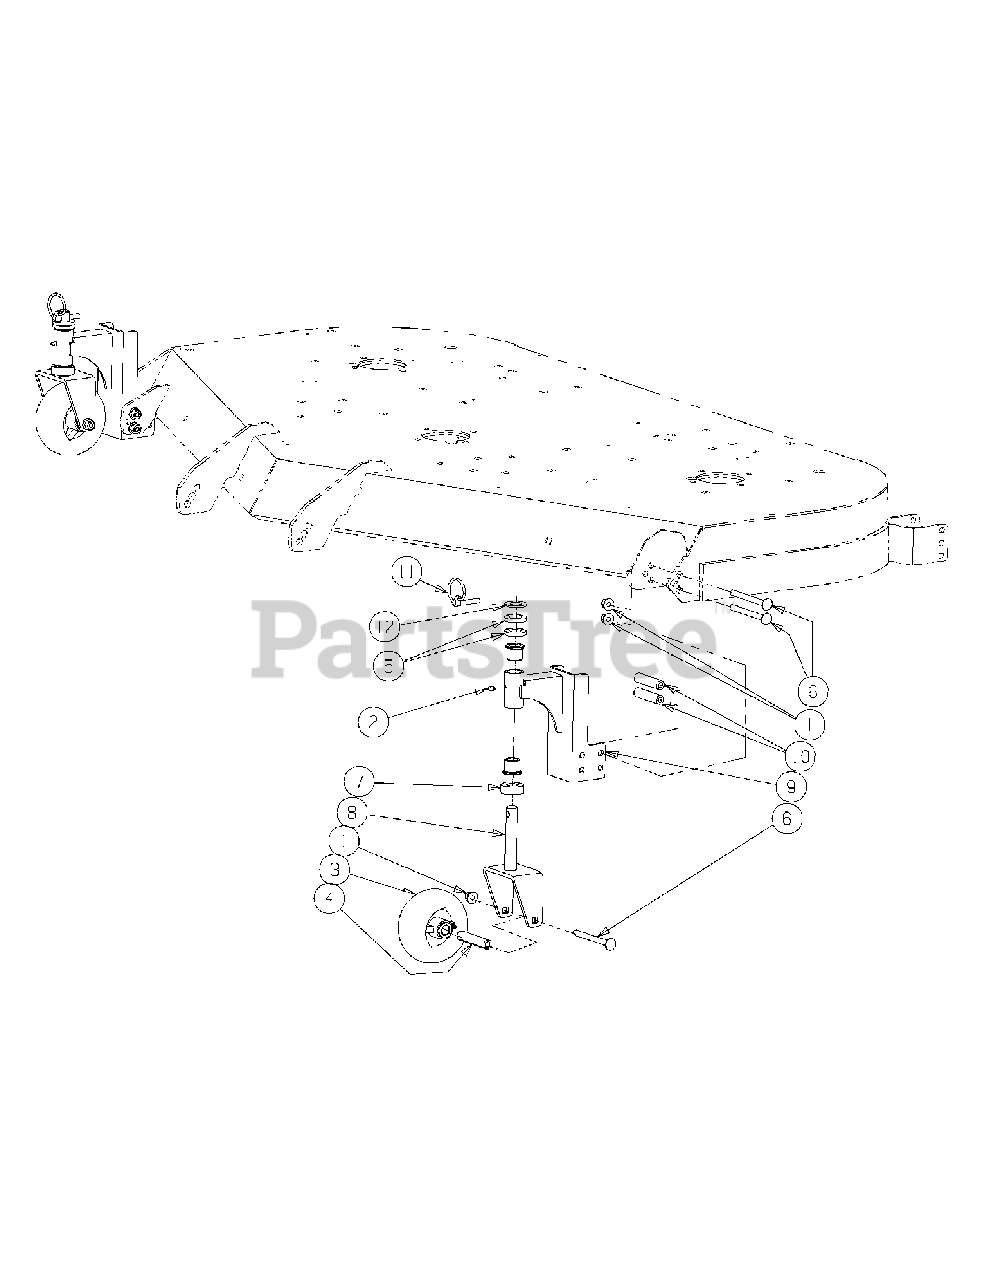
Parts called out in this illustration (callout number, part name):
1	Hex Nut, 3/8-16 Flange Lock
2	Grease Fitting, 1/4-28 x 3/16
3	Complete Wheel, 5.00 Dia.
4	Wheel Spacer
5	Spacer .812 ID x .268 LG
6	Carriage Bolt, 3/8-16 x 4.00
7	Spacer, .760 x 1.50 x .50
8	Caster Yoke Assembly
9	Caster Bracket Assembly
9	Flange Bearing
10	Spacer, .390 x .630 x 2.60
11	Lynch Pin, 5/16 x 1.562
12	Washer, .76 x 1.49 x .06
